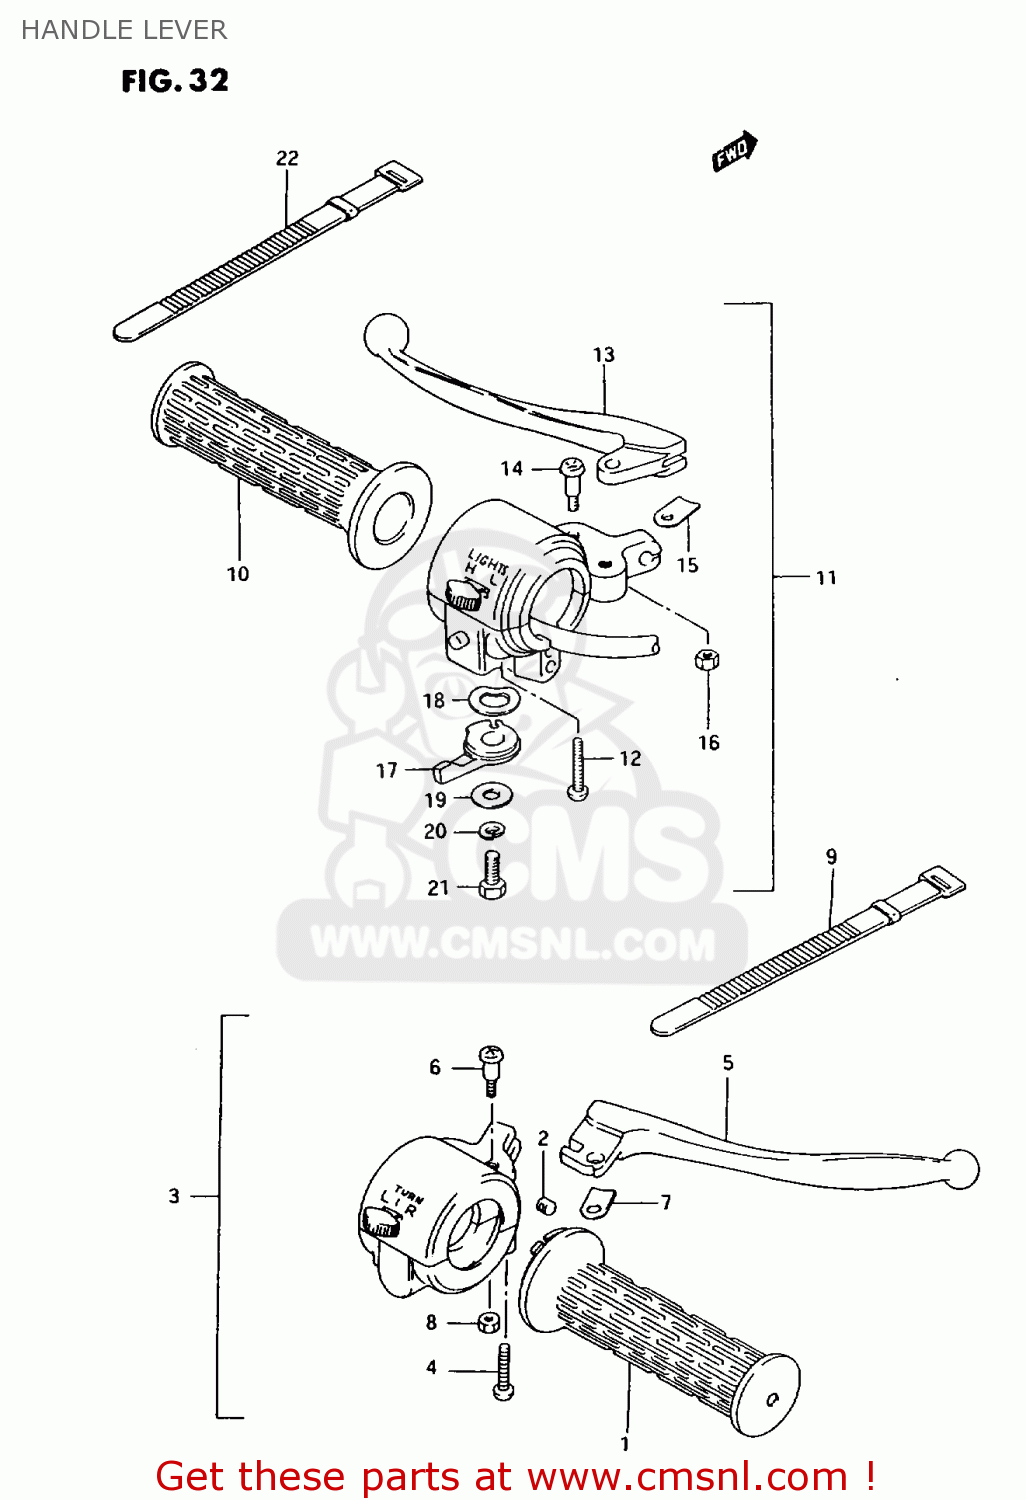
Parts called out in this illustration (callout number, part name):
1	GRIP,THROTTLE
2	PIECE,THROTTLE END
3	BRAKE LEVER & SWITCH ASSY
4	SCREW
5	LEVER,BRAKE
6	BOLT,LEVER PIVOT
7	SPACER,LEVER
8	NUT
9	CLAMP(L:120)
10	GRIP,L
11	CLUTCH LEVER,SWITCH
12	SCREW
13	CLUTCH LEVER
14	BOLT,LEVER PIVOT
15	SPACER,LEVER
16	NUT
17	LEVER,STARTER
18	WASHER,ADJUSTER
19	WASHER,STARTER LEVER
20	WASHER,LOCK
21	BOLT
22	CLAMP(L:120)
